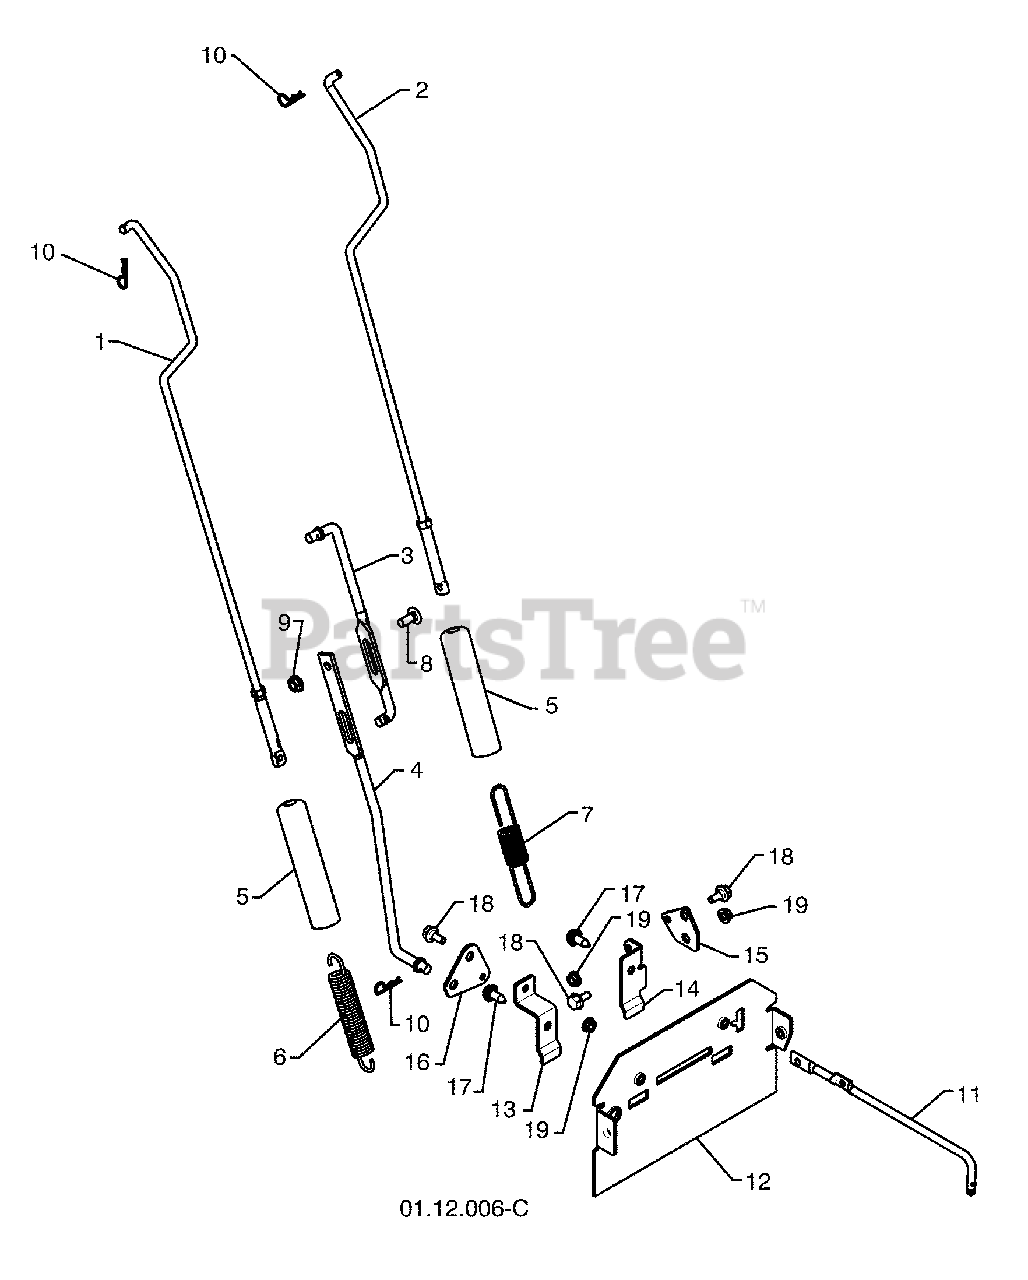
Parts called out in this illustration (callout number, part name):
1	IMPELLER ROD ASSEMBLY
2	TRACTION ROD ASSEMBLY
3	SHIFTER ROD TOP
4	SHIFTER ROD BOTTOM
5	SPRING SLEEVE
6	IMPELLER SPRING
7	TRACTION SPRING
8	CARRIAGE BOLT 5/16--18 X .750
9	NUT 5/16--18
11	CLUTCH ROD
12	REAR PLATE
13	SHIFTER PLATE BRACKET
14	CLUTCH PLATE BRACKET
15	CLUTCH PLATE
16	SHIFTER PLATE
17	BOLT 5/16--18 X .750
18	SHOULDER BOLT 1/4--20 X .500
19	NUT 1/4-20
